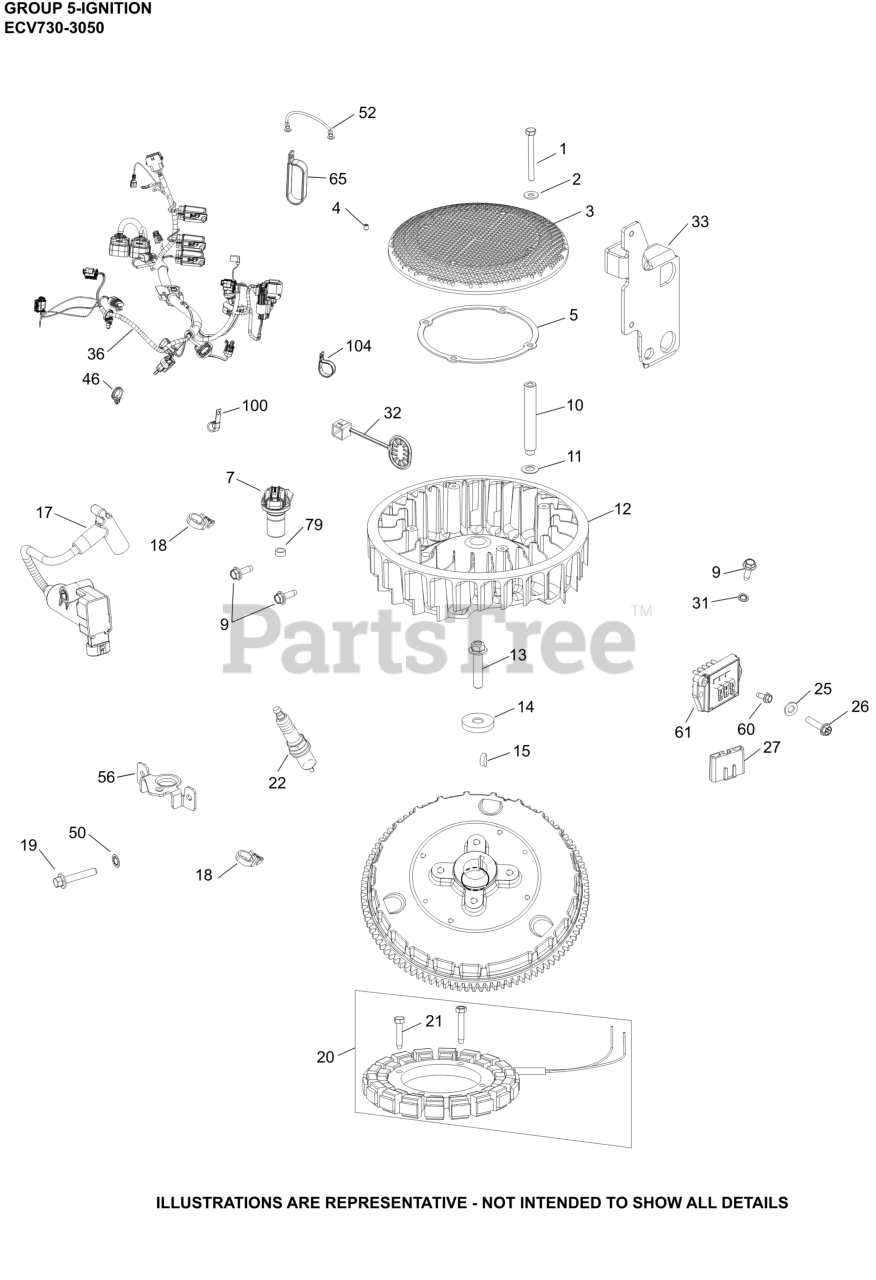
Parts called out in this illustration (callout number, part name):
1	SCREW, CAP M6X1.0X99.5
2	WASHER, FLAT 1/4" (O.D. 5/8")
3	SCREEN, GRASS
4	SCREW, SKT SET #10-24X1/4"
5	RING, SUPPORT
7	SENSOR, SPEED
9	SCREW, THREAD FORMING
11	WASHER, SPRING 10 MM
13	SCREW, HEX FLANGE
14	WASHER, FLAT
15	KEY, 3/16" X 5/8"
17	COIL, IGNITION - EFI
19	SCREW, HEX FLANGE
20	KIT, 15 / 20 AMP STATOR
21	SCREW, THREAD FORMING
22	SPARK PLUG, RFI
25	WASHER, FLAT 1/4" (O.D. 1/2")
26	SCREW, HEX FLANGE HI-LO
27	CONNECTOR
31	WASHER, INT TOOTH LOCK #10
32	CAP, CONNECTOR
33	BRACKET, ECU
36	HARNESS, WIRING ASSEMBLY
46	RETAINER, WIRE HARNESS
50	WASHER, INT TOOTH LOCK 1/4"
56	BRACKET, SENSOR
60	SCREW, THREAD FORMING
61	REGULATOR, RECTIFIER (20-30AMP,FW W/OVP)
65	CLAMP, INSULATED DOUBLE
100	CLIP, CABLE (KM)
104	CLAMP, INSULATED
NI	FLYWHEEL, ASSEMBLY-USE 24 025 115-S
NI	MODULE, ECU ECV730
